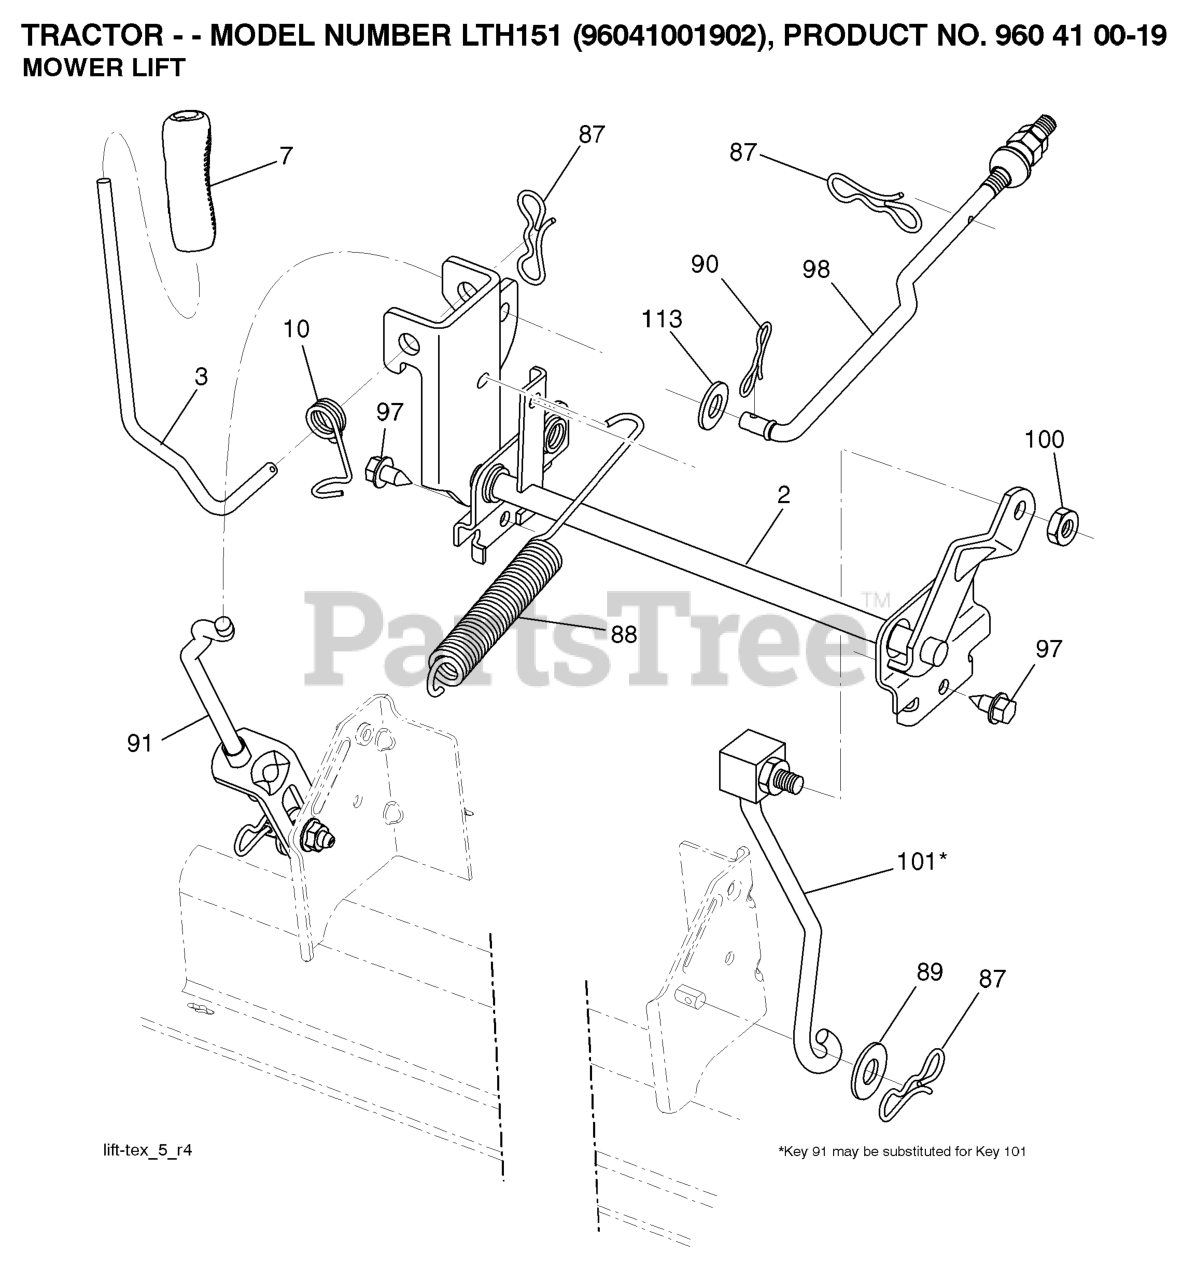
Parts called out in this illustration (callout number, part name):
2	SHAFT.ASM.LIFT.CROSS.H
3	LEVER.LIFT.HANDLE.LT
7	GRIP.HANDLE.LIFT.PVC.BLACK
10	SPRING.TORSION.LIFT.HANDLE
87	PIN.COTTER.7/16.BOW TI.
88	SPRING.LIFT.ASSIST
89	WASHER.CLEAR.ZINC
90	PIN.COTTER.5/16.BOW TI
91	LINK.ASM.LIFT.REAR
97	SCREW 3/8-16X3/4
98	LINK.ASM.SUSP.FRONT.MW
100	LOCKNUT
